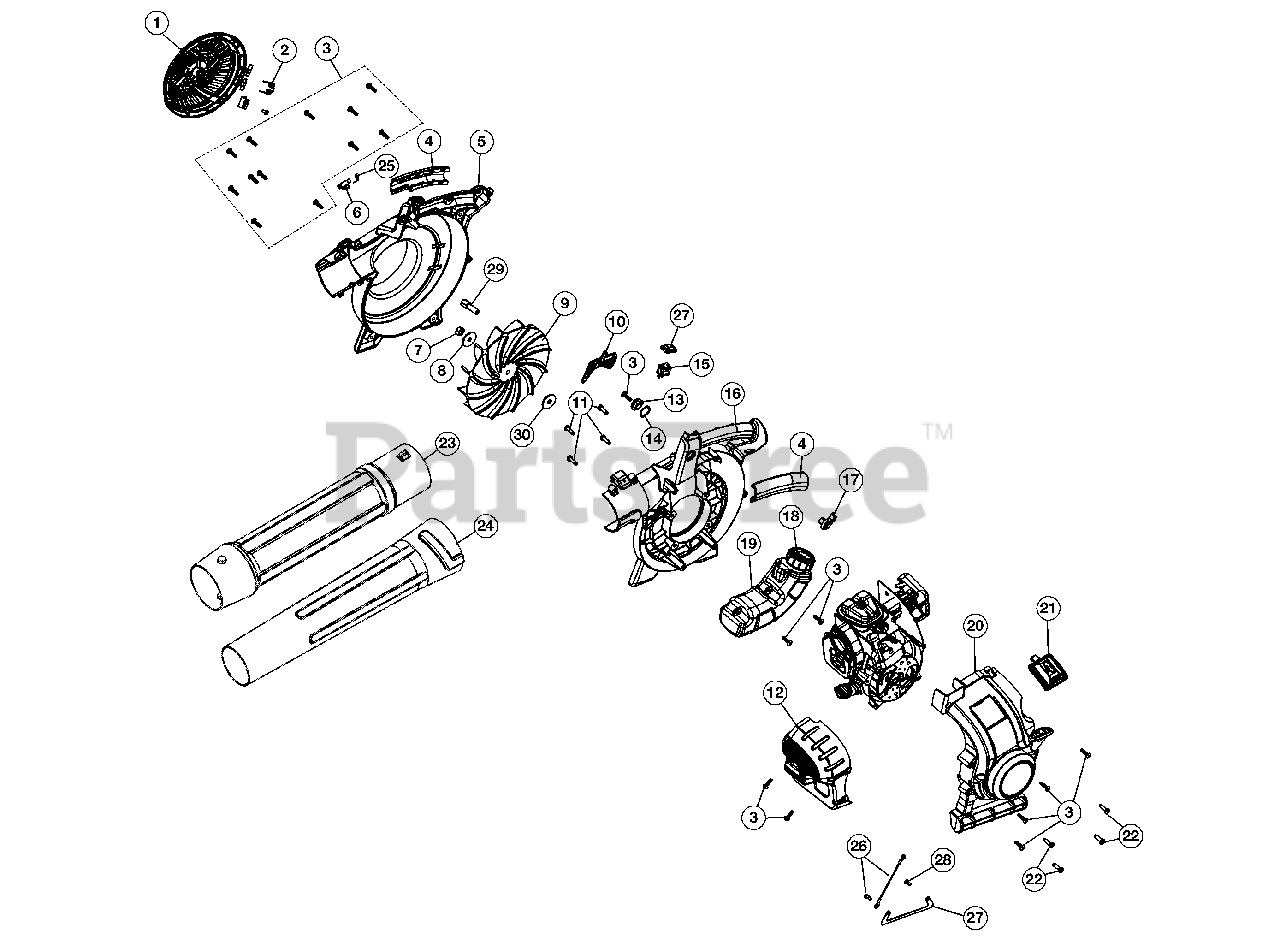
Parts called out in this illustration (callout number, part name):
1	Intake Cover Assembly
4	Handle Grips
5	Impeller Housing (Incl. 4)
6	Latch Tube
10	Throttle Trigger
11	Screw
12	Muffler Cover (Incl. 3)
13	Inner Trigger Lock
14	Wavey Washer
16	Impeller Housing (Incl. 4)
17	Outer Trigger Lock
19	Fuel Tank Assembly (Incl. 18)
20	Engine Cover Assembly (Incl. 3, 21 & 22)
21	Spark Plug Cover
23	Upper Tube
24	Lower Tube
25	Latch Spring
26	Wire Ground
27	Strap Ground
28	Screw
